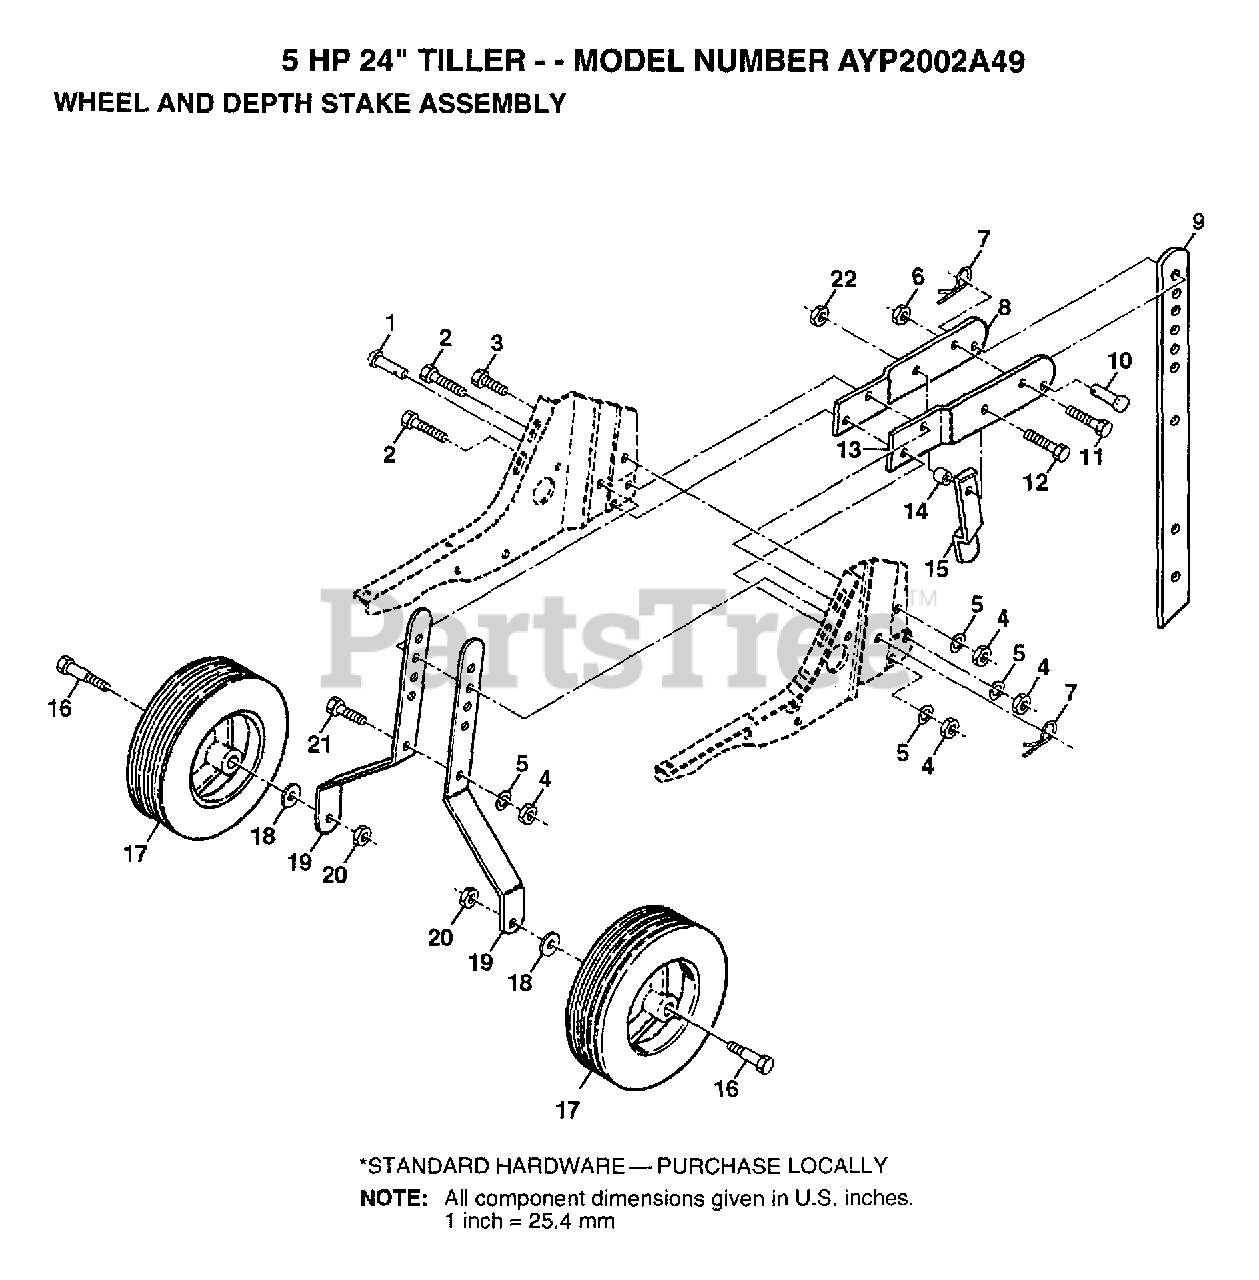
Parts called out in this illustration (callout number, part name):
1	DRILLED RIVET RT
3	BOLT
4	NUT.HEX.5/16-18
5	LOCKWASHER
6	NUT
7	SPRING.RETAINER
11	BOLT
12	BOLT.HEX.5/16-1.5
14	WASHER
15	STAKE SPRING TI
16	BOLT SHOULDER
18	WASHER
22	NUT
